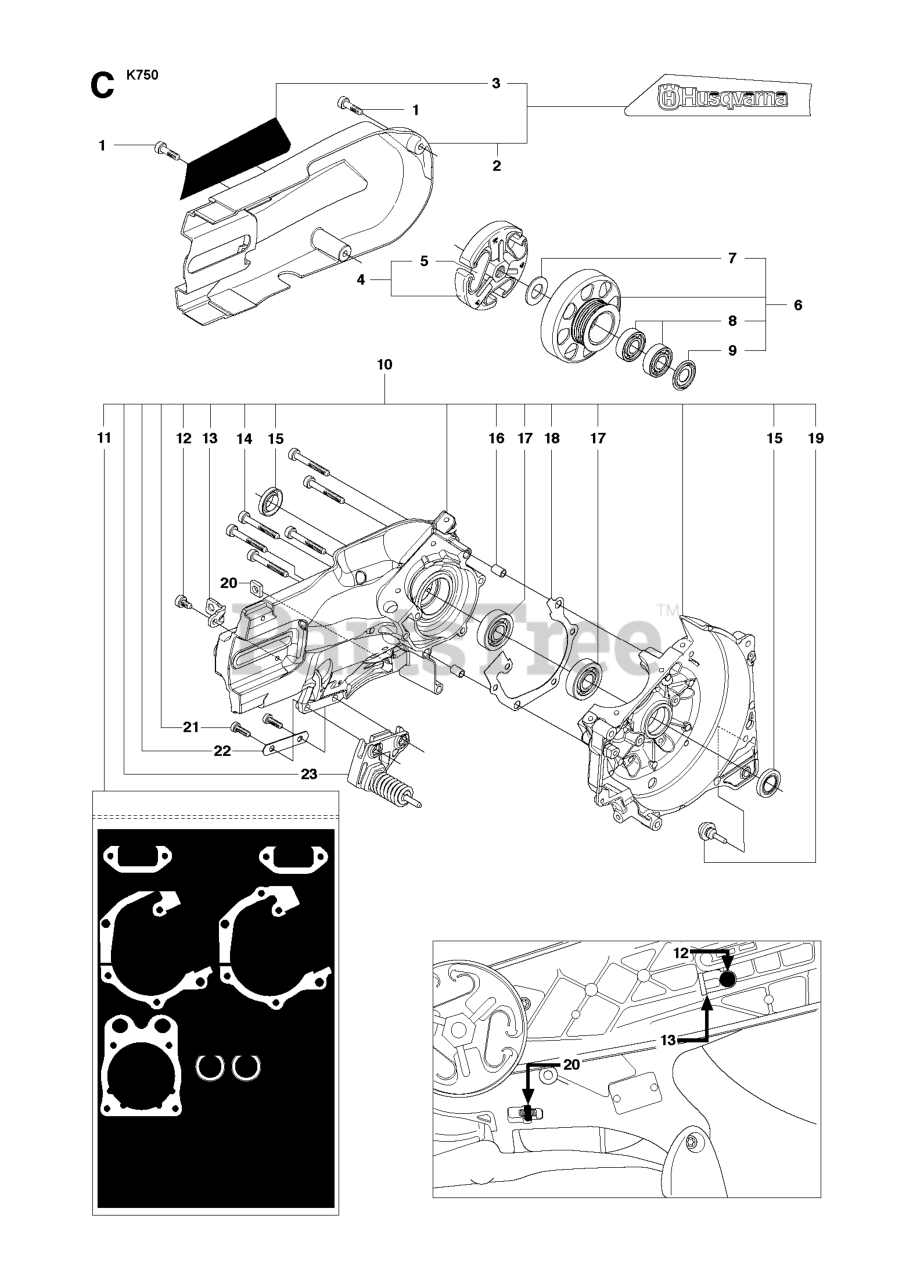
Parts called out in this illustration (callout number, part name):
2	%BELT GUARD ASSY REAR K750
4	CLUTCH ASSY
5	CLUTCH SPRING
6	DRIVING PULLEY ASSY
7	WASHER
8	HOLDER BALL BEARING
9	DUST COVER
10	CRANKCASE ASSY
11	GASKET KIT
15	SEALING RING
17	BALL BEARING-6202-C3 SKF
23	SPRING RETAINER
25	GASKET
29	RP GASKET CARBURETOR
